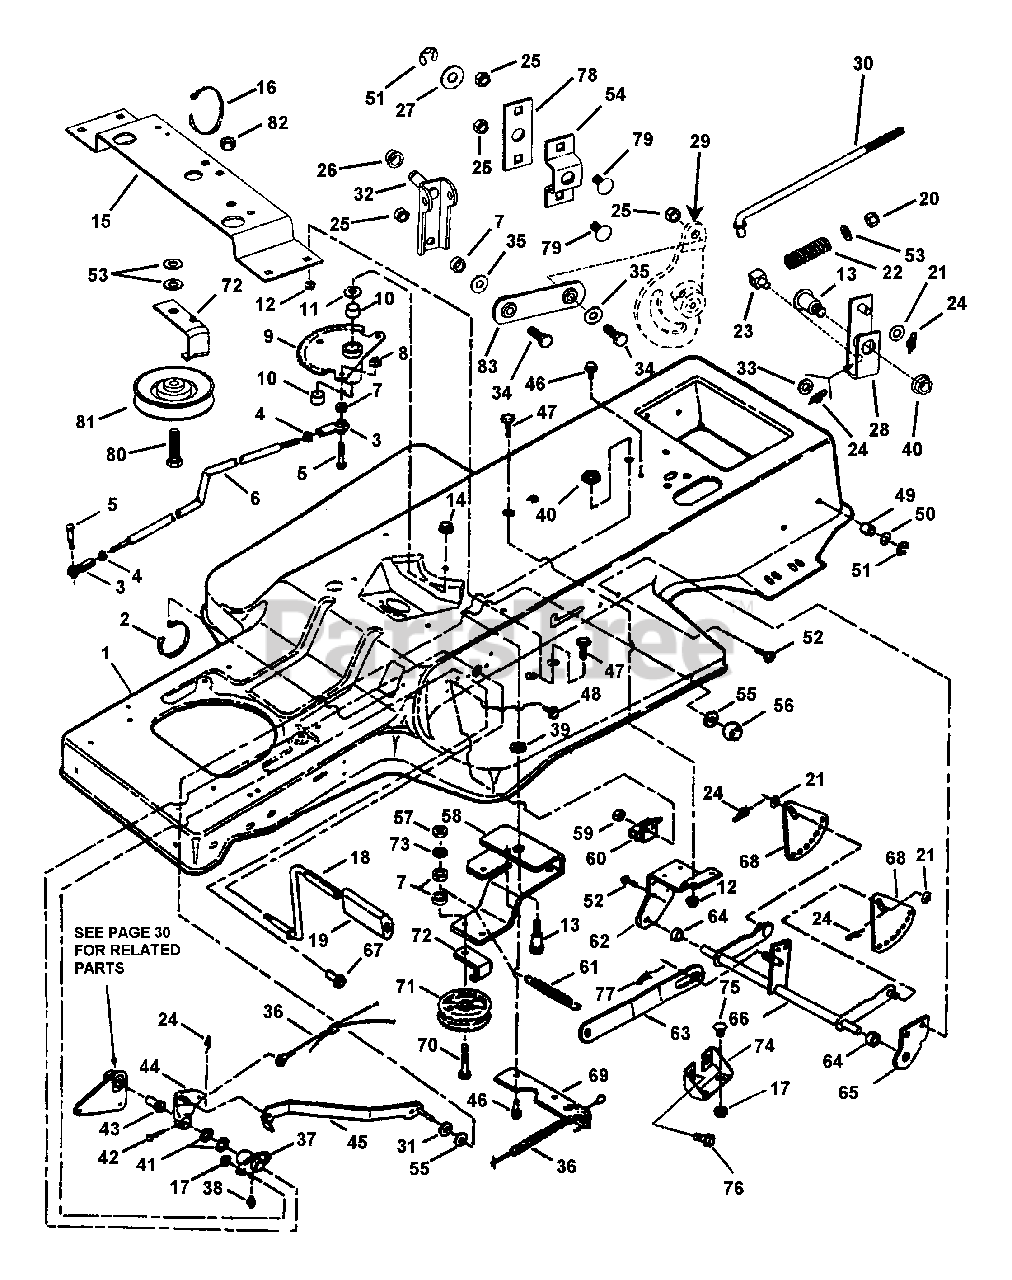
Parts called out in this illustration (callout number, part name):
1	FRAME, Tractor
2	TIE, Wire
3	ROD END
4	NUT, 3/8-24 Hex Jam
5	SCREW, 3/8-24 x 1-1/4" Hex Cap
6	LINK, Drag
7	SPACER
8	NUT, 3/8-16 Hex Flange Lock
9	ASSEMBLY, Sector Gear
10	BEARING, Sector Gear
11	WASHER, 3/4" Thrust
12	NUT, 1/4-20 Hex Flange Lock
13	BOLT, 1/2-13 x 2" Shoulder
14	NUT, 1/2-13 Hex Center Lock Gr. A
15	BRACE, Sector Gear
16	TIE, Cable 7"
17	NUT, 5/16-18 Hex Flange Lock, Gr. 5
18	PEDAL, Clutch Brake
19	PAD, Pedal
20	NUT, 3/8-16 Hex Nyloc
21	WASHER, 3/8 Bright Zinc, Flat
22	SPRING, Brake
23	SWIVEL, Inline Brake
24	PIN, 3/8 x 1-7/32" Cotter (Self-Locking)
25	NUT, 5/16-18 Hex Center Lock
26	BUSHING, 7/16" I.D.
27	WASHER, .44" I.D. Flat
28	WELDMENT, Brake Arm
29	ARM, Speed Control
30	ROD, Brake
31	WASHER, 5/16" Flat
32	WELDMENT, Pivot Shift Lever
33	WASHER, .406 I.D. Flat
34	SCREW, 5/16-18 x 1-1/4" Grade 5
35	WASHER, 5/16" Flat
36	ASSEMBLY, Clutch/Brake Cable
37	ASSEMBLY, Foot Shaft Pivot
38	LUBE FITTING, Straight (press-fit for .187 dia. Hole)
39	WASHER, 1/2" Internal Tooth Lock
40	NUT, 1/2-13 Hex Flange Lock
41	WASHER, 5/8" Flat
42	PIN, 3/16 x 1-1/2" Clevis
43	BEARING, Flange
44	WELDMENT, Clutch Brake Arm
45	LATCH, Park Brake
46	SCREW, 5/16-18 x 5/8" Self-Tap
47	BOLT, 1/4-20 x 5/8" Carriage
48	SCREW, #10-32 x 5/8" Self-Tap.
49	BUSHING, 1/2" Nylon
50	WASHER, 1/2" Flat
51	RING, 1/2" External Retaining
52	SCREW, 5/16-18 x 5/8" Truss
53	WASHER, 3/8" Flat
54	BRACKET, Pivot Mounting
55	WASHER, 5/16" Nylon
56	KNOB, Clutch/Brake (5/16-18)
57	NUT, 3/8-16 Hex, Grade B or 5
58	ARM, Idler
59	NUT, #10-32 Hex Nyloc
60	SWITCH, DPDT NC/NO
61	SPRING, Traction Drive
62	BRACKET, Rear Lift/PTO Lever
63	LINK, Lift (33" Deck)
65	BRACKET, Deck Hang Pivot
66	WELDMENT, Rear Lift Arm
67	SCREW, 5/16-18 x 7/8" Truss Head (Torx)
68	PLATE, Lift Sector
69	EXTENSION, Idler Arm
70	SCREW, 3/8-16 x 2-1/2" Cap Grade 5
71	PULLEY, Flat Idler, 3.47" O.D.
72	GUIDE, Pulley
73	WASHER, 3/8" Split Lock
74	BRACKET, Frame Brace
75	BOLT, 5/16-18 x 5/8" Short Neck Carriage, Grade 5
76	SCREW, 5/16-18 x 3/4" Self-Tap
77	COTTER PIN, 1/16 x 1-7/32" Self Lock
78	BRACKET, Mounting Brace
79	BOLT, 5/16-18 x 3/4" Carriage,
80	SCREW, 3/8-16 x 1-1/2" Cap, Grade 5
81	PULLEY, Idler V 3.30
82	NUT, 3/8-16 Hex Center Lock
83	LINK, Fwd/Rev
